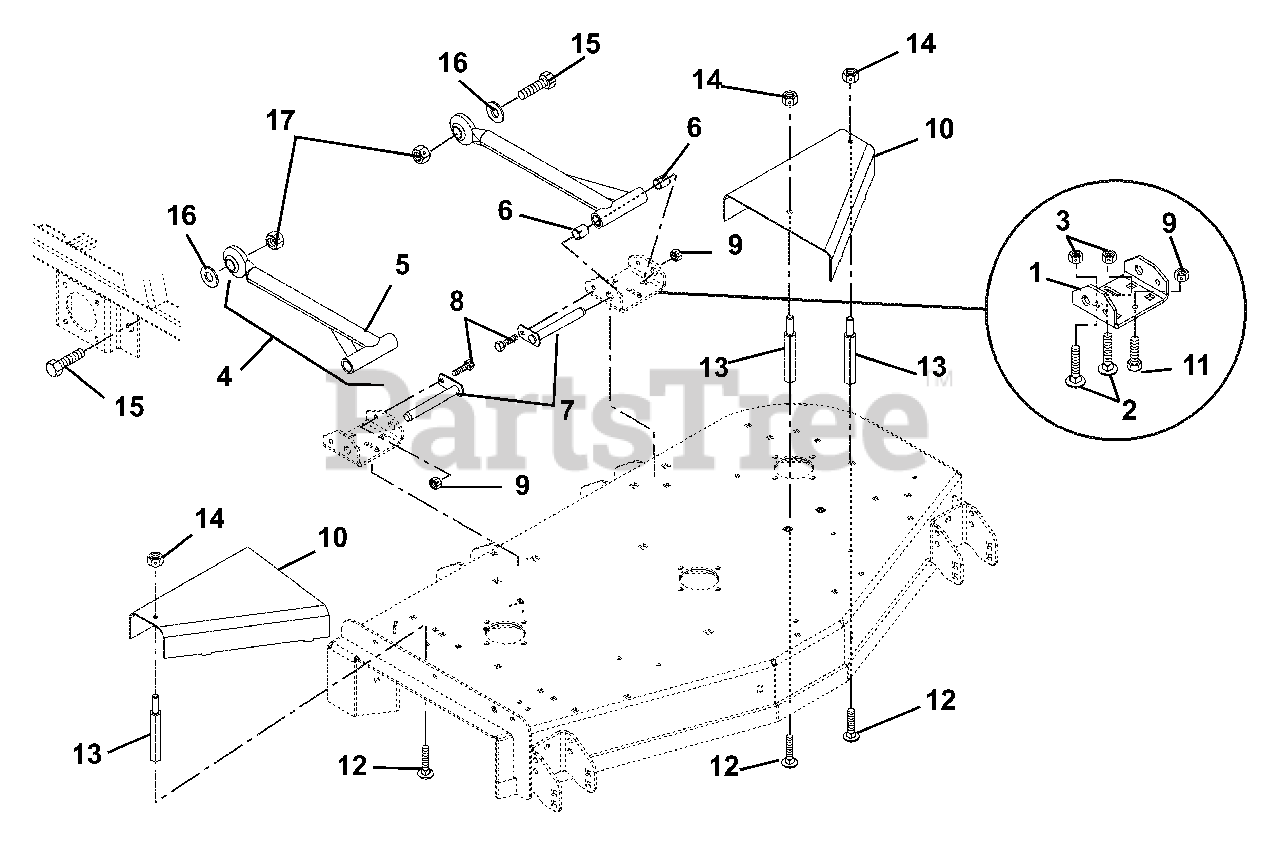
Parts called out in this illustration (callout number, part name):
1	Bracket, Mower Mounting (Rear)
2	Bolt, Round Head Square Neck .50-13 x .75 Grade 5
3	Nut, Locking Center Jam .50-13
4	Assembly, Mower Mounting Arm
5	Weldment, Mower Mounting Arm
6	Bearing .75 x .875 x 1.00
7	Weldment, Mower Mounting Pin
8	Bolt, Hex .38-16 x 1.00 Grade 5
9	Nut, Locking Top Flange .38-16
10	Guard, Pulley Left Hand
10	Guard, Pulley Right Hand
10	Guard, Right Hand Pulley
10	Guard, Left Hand Pulley
11	Bolt, Round Head Square Neck .38-16 x .75 Grade 5
12	Bolt, Round Head Square Neck .31-18 x .75
13	Standoff 2.75 x 5/16-18
14	Nut, Locking Top Flange .31-18
15	Bolt, Hex .875-9 x 2.75 Grade 5
16	Washer, Flat Steel .875 x 1.50 x .120
17	Nut, Locking Center .875-9
